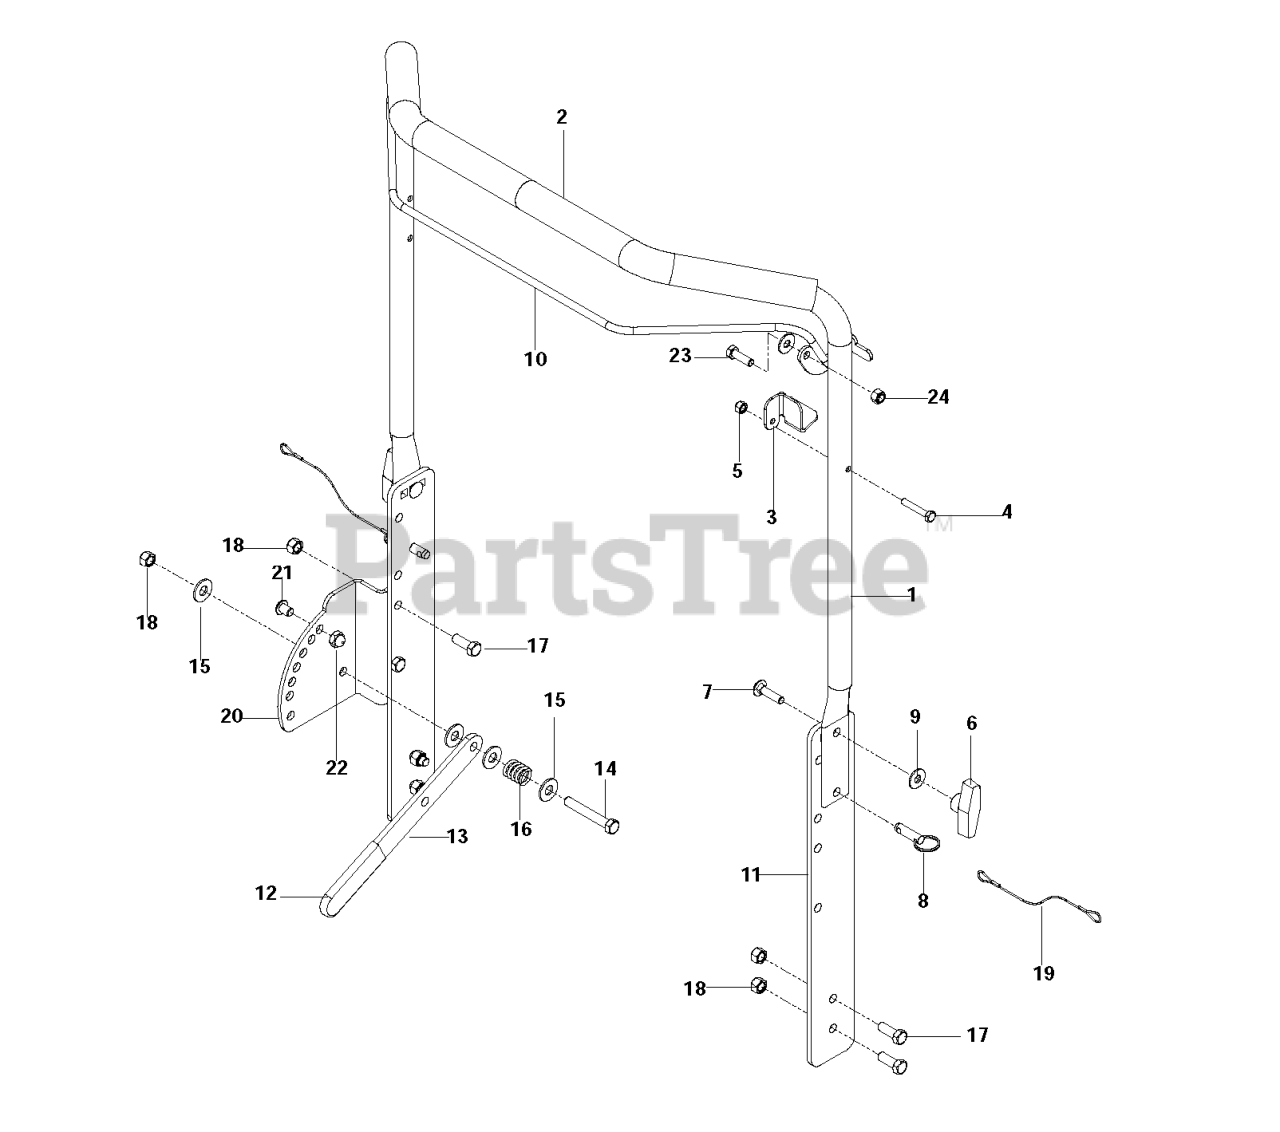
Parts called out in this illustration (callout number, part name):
1	HANDLE GRAY
3	CABLE TAB POWER RAKE
4	SCW 1/4-20 X 1-1/2 HEX
5	NUT.1/4-20.HEX.NYLOC.ZD
7	BOLT, CARRIAGE 5/16X1-1/4
8	DETENT PIN RAKE/DT
9	WASHER 5/16 FLAT
10	BAIL - ORANGE
11	HANDLE SIDE GRAY
13	LEVER, PLATED
14	HCS 3/8C X 2 1/2
15	WASHER 3/8 FLAT
16	COMPRESSION SPRING
17	HCS 3/8-16X1.GRD.5.ZD
18	NUT 3/8-16 NYLOC
20	HEIGHT ADJUSTMENT PLATE
21	BLT 3/8-16 X 1/2 BTN HD BLK SP
22	NUT 3/8-16 ACORN HEX
23	HCS 5/16C X 1
24	NUT 5/16 NYLOC
